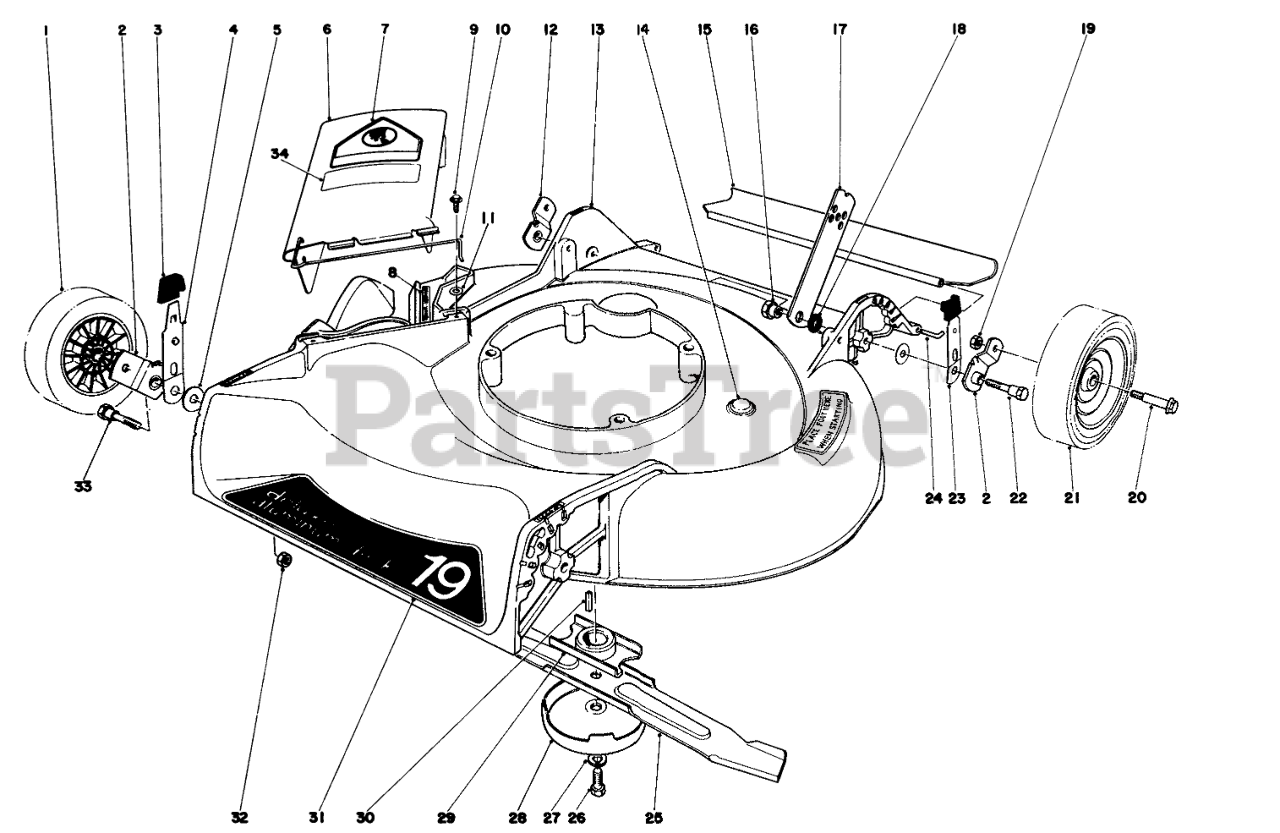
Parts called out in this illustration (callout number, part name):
1	Wheel & Tire Assembly
2	Pivot Arm
3	KNOB-ARM
4	SPRING ARM ASM
5	Washer
6	Deflector-Cover Assembly (Incl. Ref. #7,10 & 34)
7	DECAL-DANGER
8	Decal
9	SCREW
10	SPRING HINGE
11	WASHER-FLAT
12	Pivot Arm
13	Housing
15	Rear Shield
16	HANDLE PIVOT NUT
17	Handle Latch
18	HANDLE LATCH SPACER
19	Nut
21	Wheel & Tire Assembly
22	PIVOT SCREW
23	SPRING ARM ASM
24	SHIELD ROD
25	Blade
26	SPECIAL SCREW
27	WASHER-LOCK
28	AntiScalp Cup
29	Blade Retailer
30	KEY-SQUARE
31	Decal
32	Nut
33	PIVOT SCREW
34	DECAL DEFLECTOR
